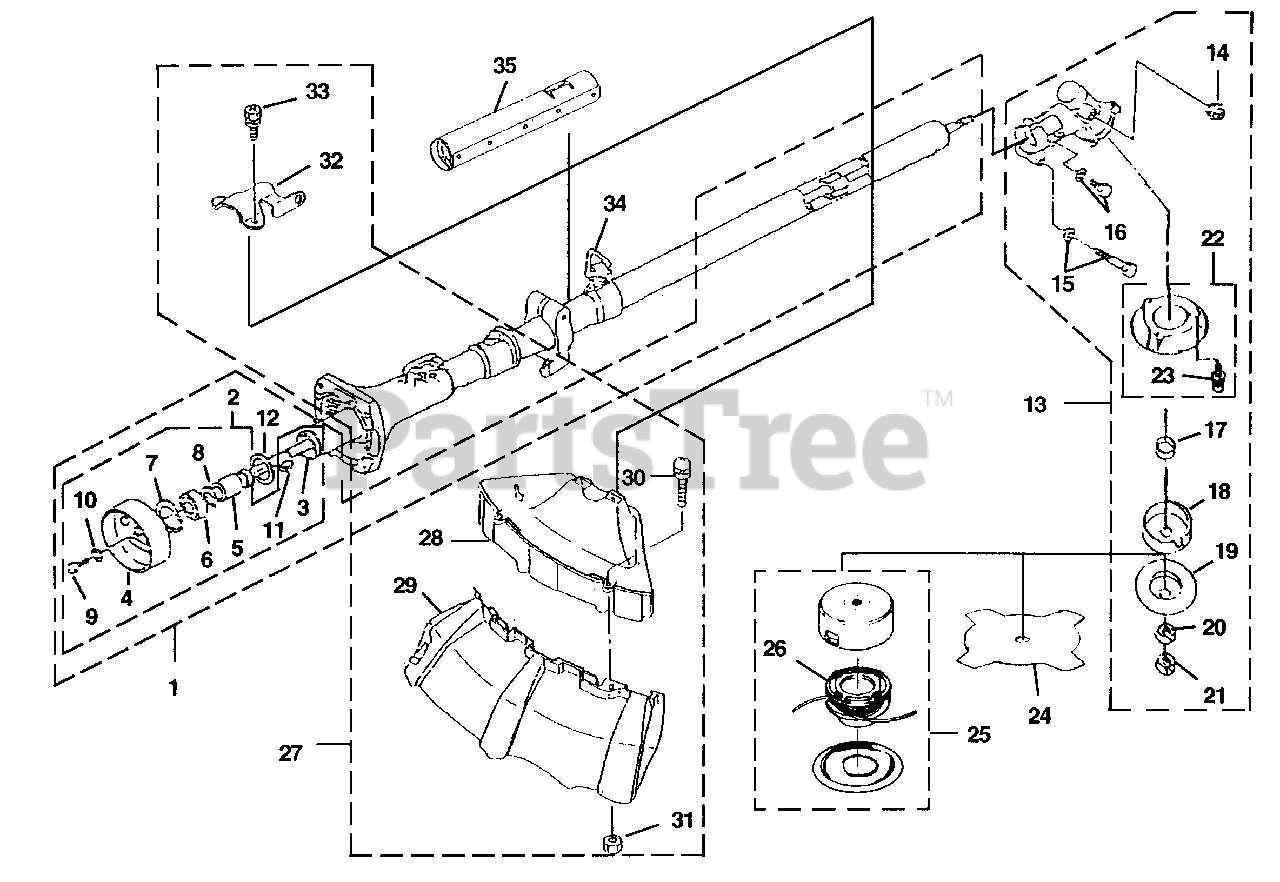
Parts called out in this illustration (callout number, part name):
1	DRIVESHAFT HSG
2	DRIVESHAFT ASSY
3	DRIVESHAFT
4	CLUTCH DRUM
6	BEARING, BALL
7	SNAPPING - Inner
8	SNAPPING - Outer
11	SNAPPING - Outer
13	GEARHEAD ASSEMBLY
14	BOLT-Grease
15	BOLT (M6 X 32)
16	BOLT(M6 X 14)
18	WASHER - Flange
19	WASHER - Clamp
21	NUT
22	GRASS GUARD
23	SCREW-Socket Hd
24	BLADE - Cutter
25	STRING HEAD ASSY
26	SPOOL & STRING
27	PROTECTOR ASSY
28	PROTECTOR COMP
29	PROTECTOR COMP
30	SCREW ASSEMBLY
31	NUT
32	CLAMP, PROTECTOR
33	BOLT ASSEMBLY, CROSSRECESS
34	HANGER ASSEMBLY
